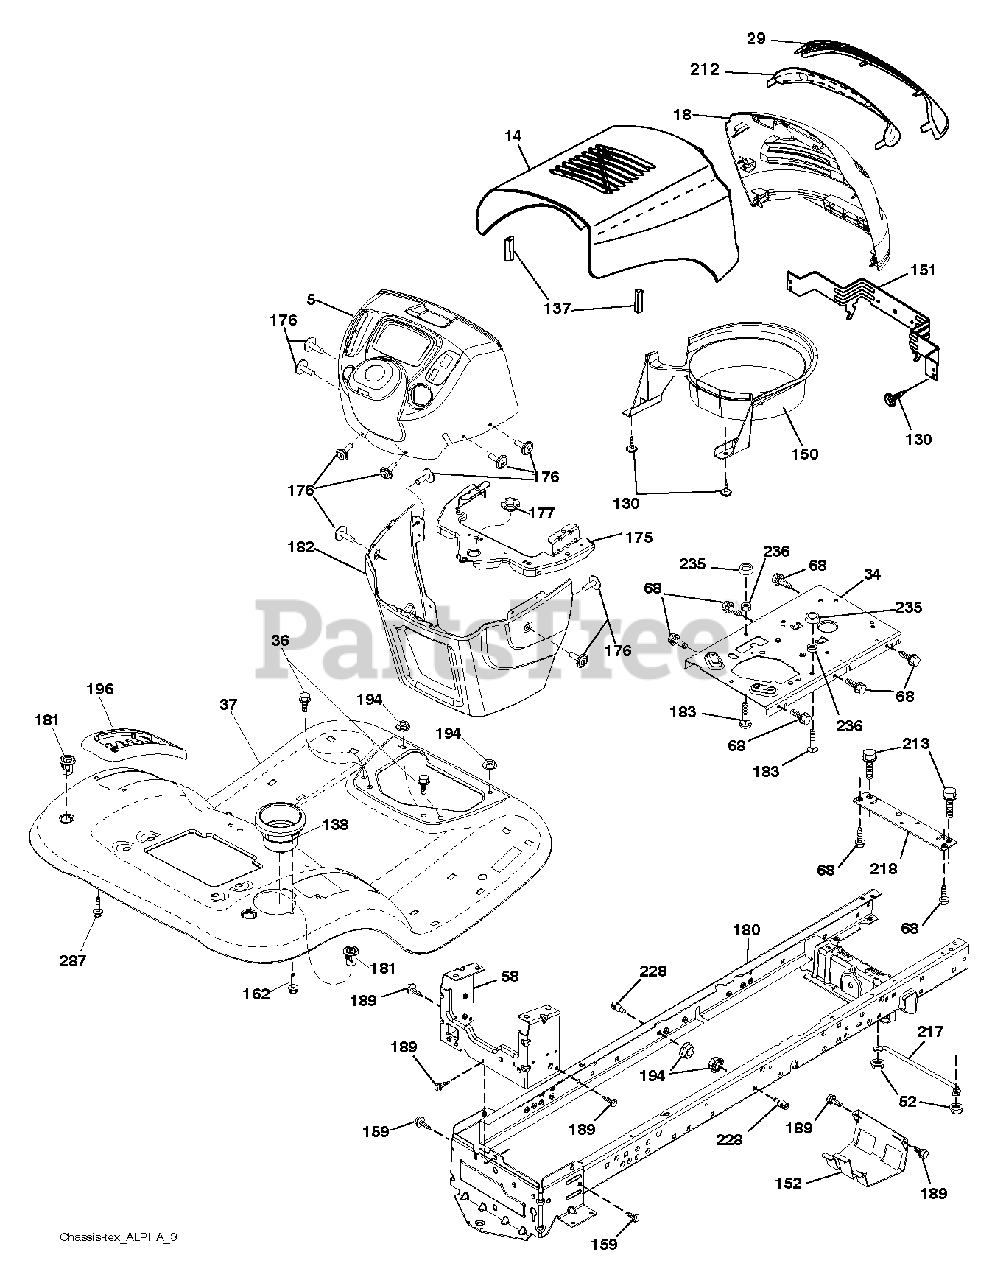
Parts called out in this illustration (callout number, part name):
5	DASH.P/L.TEX.CBL.CL.N/CHK.BLAC
14	HOOD.STEEL.ELITE.YELLOW
18	GRILLE.ELITE.BASIC.LT.BLACK
29	INSERT.LENS.REFLECTIVE.LEFT
36	SCREW 5/16"
52	LOCKNUT
58	DRAWBAR UPPER 2PC SMALL FENDER
68	SCREW LT
130	SCREW.#10 X 0.750.BOS (2 2)
137	BUMPER.HOOD.LARGE.1.75"
138	CUPHOLDER.TL.TEX.BLACK
150	DUCT.INTAKE.AIR.KAW
151	BRACKET PIVOT
152	SHIELD.BROWNING.W/TEX
159	SCREW, 3/8-16X3/4
162	SCREW.HI-LO.CONSOLE
175	CROSSMEMBER.LT
176	SCREW.#10-24X5/8.RN.QU
177	BUSHING STEERING
180	CHASS.WLDMNT.TL.12GA/2P.48/54
181	FEND/FTRST.PCH.CPH.NFW
182	DASH.LOWER.LT.CCS
183	BOLT.5/16-18X1-1/4 FULL THD
189	SCREW
194	NUT LOCK HEX FLANGE 5/16-18
196	CONSOLE.ASM.DECKLFT.BL/RBT.TLT
212	LENS.GRILLE.BASIC.BAR.LT.CLR
213	BOLT
217	ROD.PIVOT.HOOD
218	X-PIECE.HOOD.STOP.NON/
228	STUD.FASTNER.W/ANTI-ROTATE
235	SPACER FENDER
236	NUT.CENTERLOCK.5/16-
287	SCREW 1/4X20
